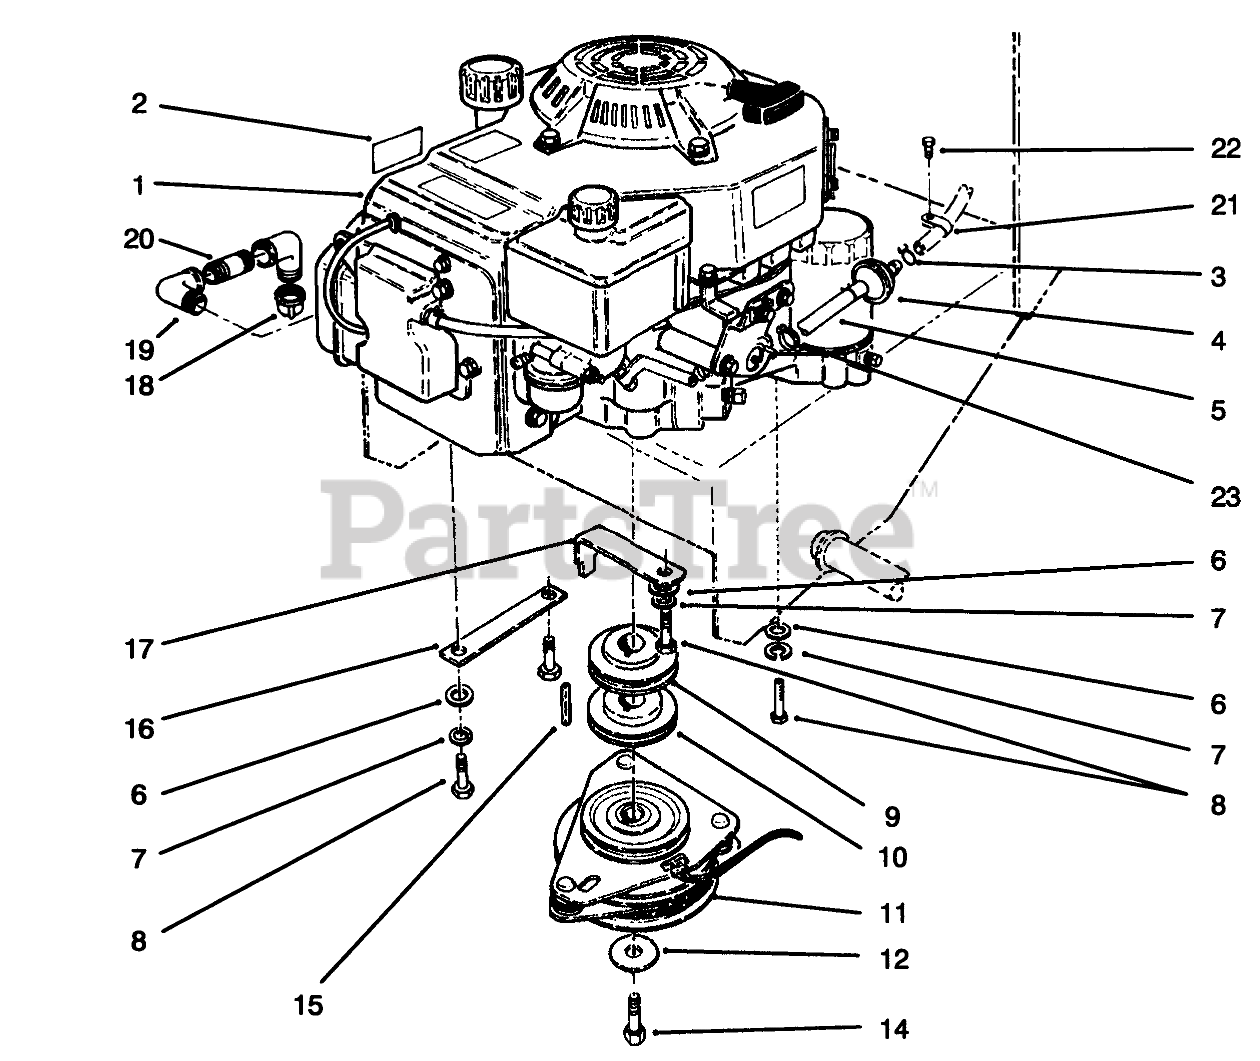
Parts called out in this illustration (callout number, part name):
2	DECAL-SURFACE, HOT
3	CLAMP-HOSE
4	FILTER-FUEL
5	HOSE-FUEL
6	WASHER-PLAIN
7	WASHER-LOCK
8	SCREW-HH
9	SHEAVE-UPPER HALF
10	SHEAVE-LOWER HALF
11	CLUTCH/BRAKE
12	WASHER
14	SCREW-CLUTCH
15	KEY-SQUARE
16	Guard-Pulley
17	Retainer-Clutch
18	CAP-PIPE
19	ELBOW-STREET, 90 DEG
20	NIPPLE
21	CLAMP-CABLE
22	SCREW-SHWH
23	CLAMP-WORM
